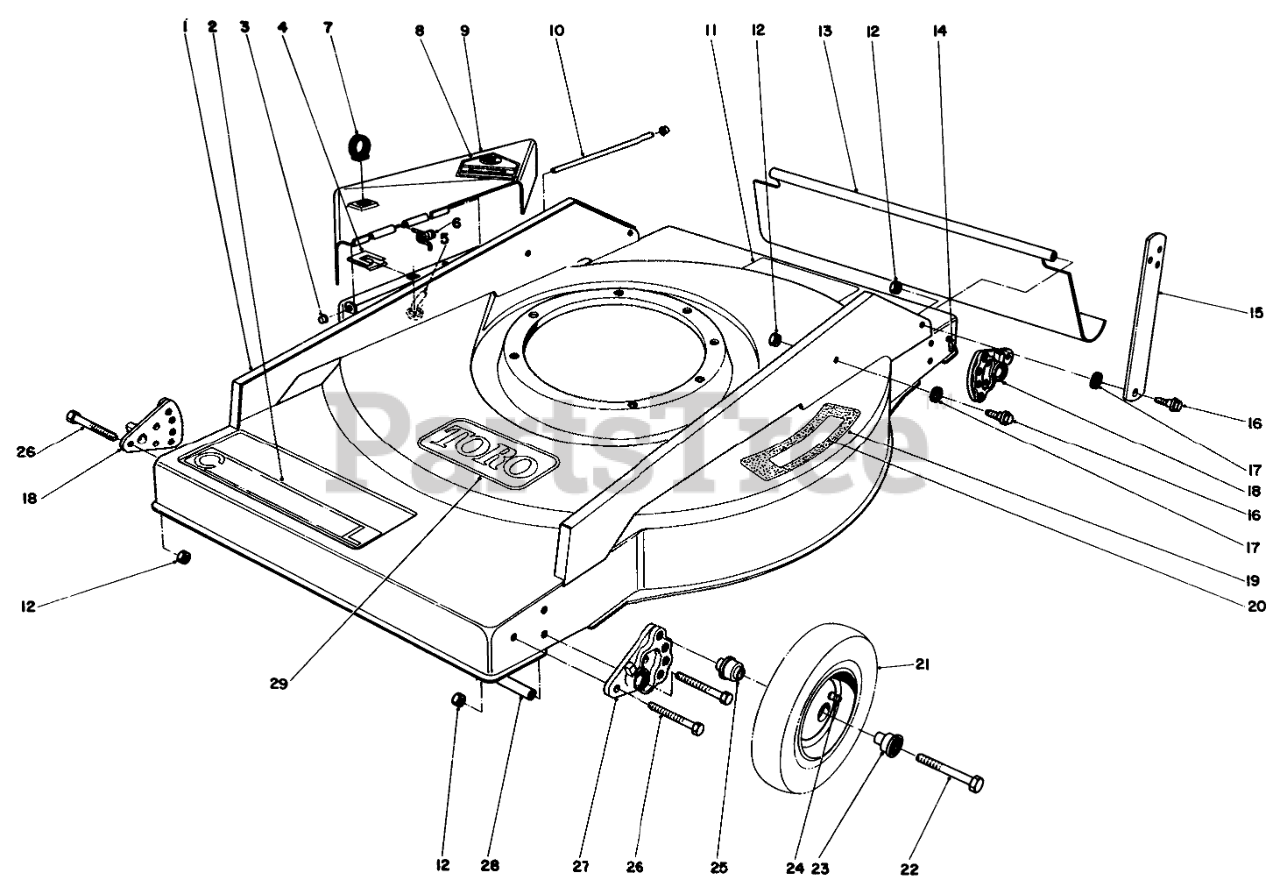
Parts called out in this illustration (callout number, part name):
1	Housing (Incl. Ref. #2, 19 & 20)
2	COMMERCIAL DECAL
3	PUSHNUT-CAP, WASHER
4	BAG CHUTE CLIP PIN
5	BAG CHUTE PIN
6	TORSION SPRING
7	LIFT LOOP
8	DECAL-DANGER
9	Deflector (Incl. Ref. #8)
10	DEFLECTOR PIVOT ROD
11	DECAL SAF INST
12	NUT-LOCK, NI
13	REAR SAFETY SHIELD
14	SHIELD ROD
15	Handle Strap
16	SCREW-SHOULDER
17	HANDLE LATCH SPACER
18	WHL QUADRANT B-MACH.
19	PAD STEP
20	Decal Step Pad
21	Wheel & Tire Assembly (Incl. Ref. #23-25)
22	SCREW-HH
23	WHEEL BRG
24	FITTING-GREASE
25	WHEEL BEARING
26	SCREW-HH
27	WHL QUADRANT A-MACH.
28	Rod-Tie
29	Decal Tow
